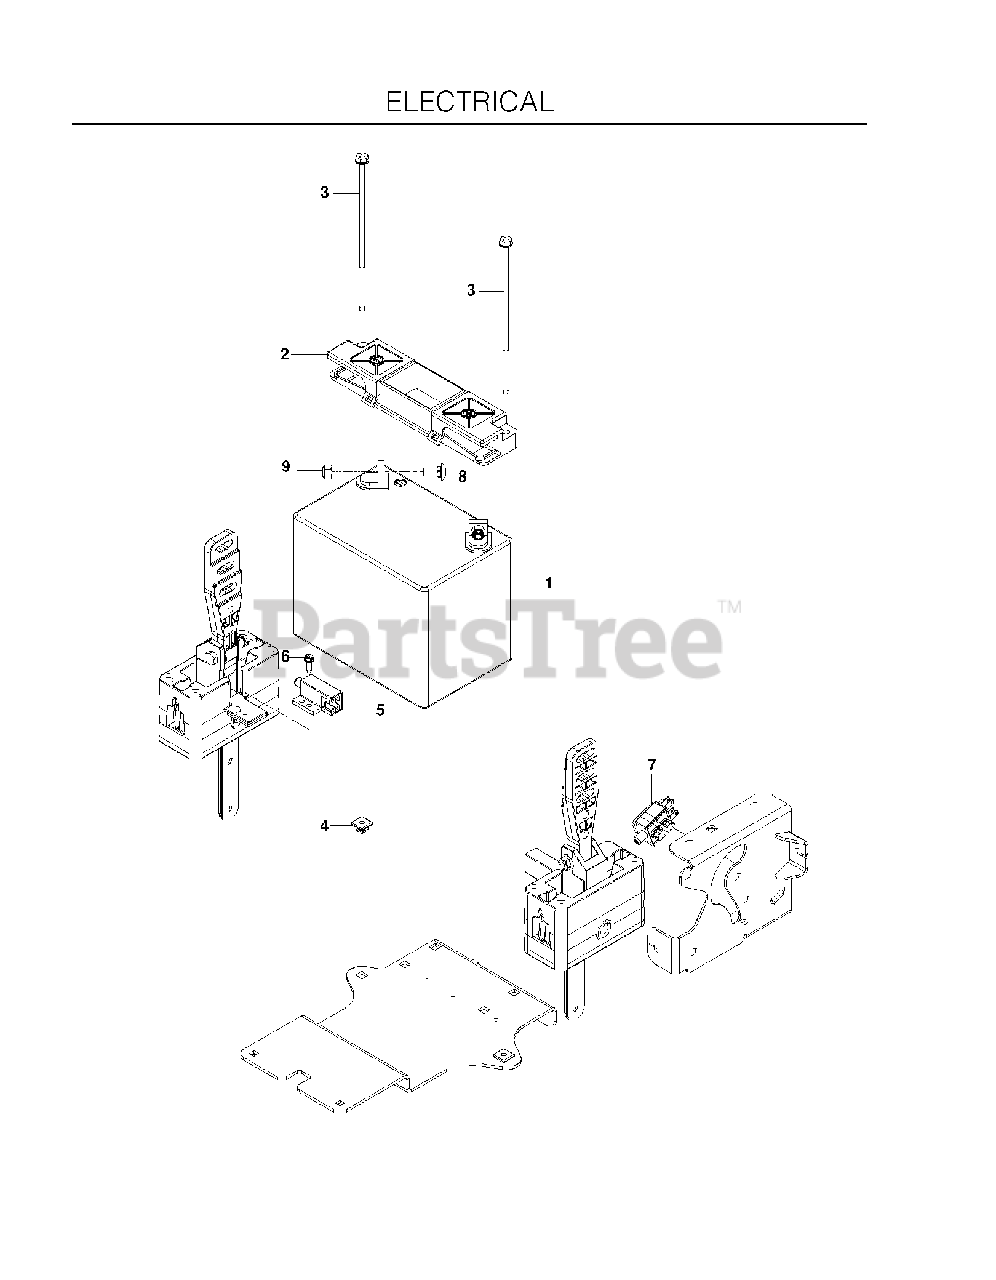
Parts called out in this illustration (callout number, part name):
1	BATTERY, 12 V 330 AMP TBR
2	BATTERY HOLD DOWN
3	BOLT - 1/4-20 X 7.5
4	PUSH NUT-NYLON
5	SWITCH, INTERLOCK
6	SCREW #10 X 1/2 SELF TAPPING
7	SWITCH, BRAKE 3P
8	BOLT 5/16C X 3/4" CARRIAGE
9	5/16-18 NYLOC FLANGE NUT
